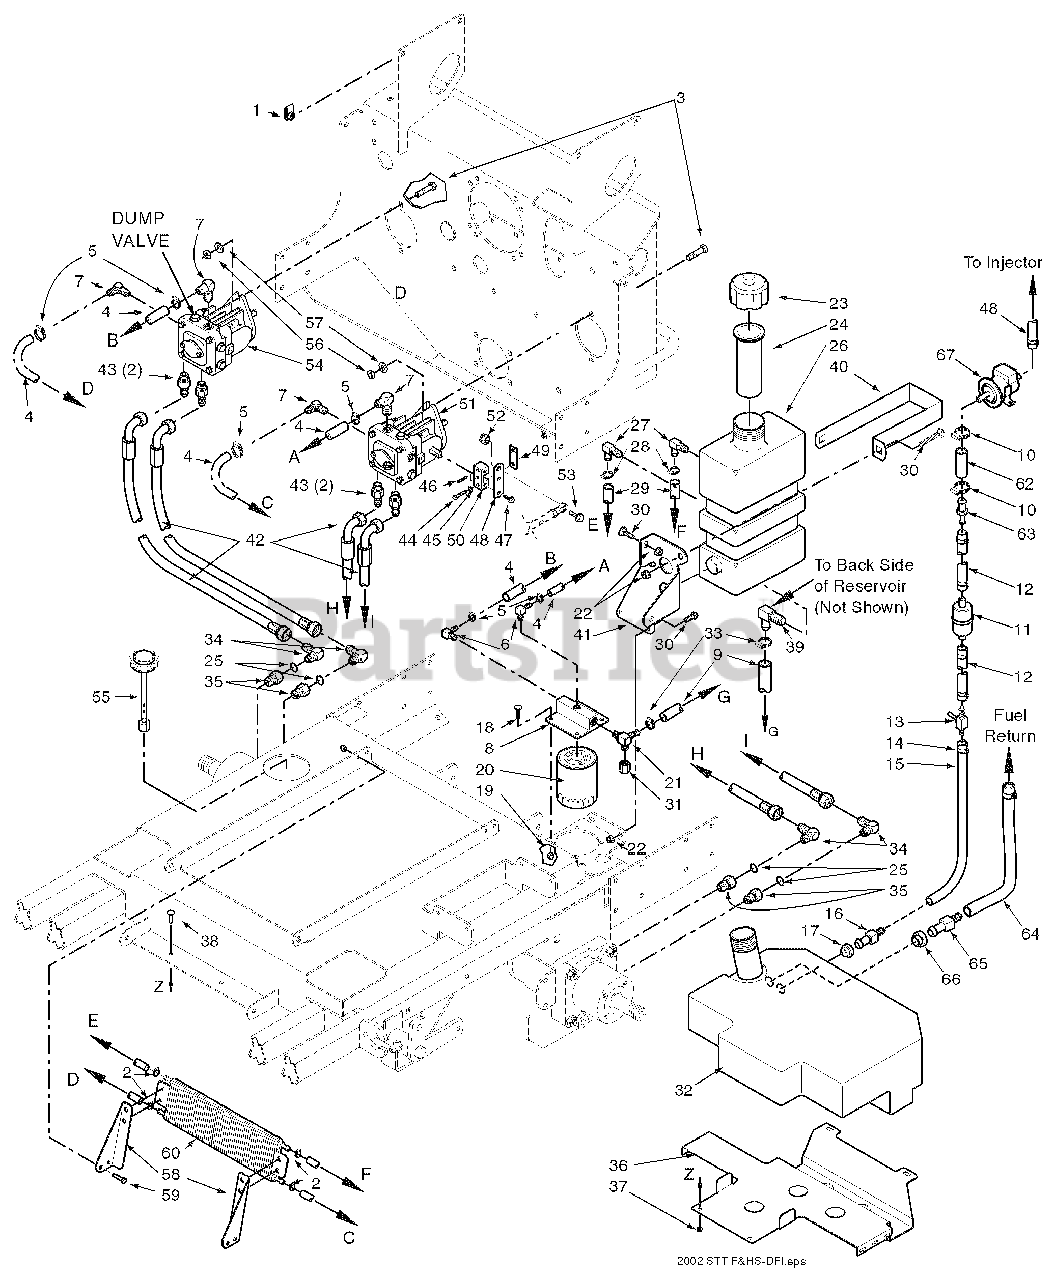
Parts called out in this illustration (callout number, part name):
1	U-Nut 1/4-20
2	Hose Clamp, 0.69 dia.
3	Bolt, Hex Head 1/4-20 x 2.0"
4	Hose, 3/8" ID Pushlock
5	Clamp, Hose 1/2"
6	Elbow, 90 Degree - 1/4 NPT x 3/8" Hose
7	Elbow, 90 Degree - 9/16 O-ring x 3/8" Hose
8	Oil Filter Base
9	Hose Assembly, 1/2" ID
10	Clamp, .87 max Dia.
11	Fuel Filter, Kawasaki
12	Fuel Hose, 5/16" ID. Non-Perm.
13	Valve, Shutoff Kawasaki
14	Clamp, Fuel Hose
15	Fuel Hose, 5/16" ID. Non-Perm.
16	Hose Fitting
17	Bushing
18	Bolt, Hex Head 5/16-18 x1.0" Zinc
19	Nut, Serrated Flange 5/16-18
20	Oil Filter
21	Tee, 3/4 O-ring x JIC x 1/2" Hose
22	Nut, Hex Elastic Stop 1/4-20
23	Cap, Hydraulic Tank
24	Insert, Filler Neck
25	O-Ring
26	Oil Reservoir Assembly
27	Elbow, 90 Degree .38 Hose
28	Hose Clamp, 0.69 dia.
29	Hose, 3/8" ID, Pushlock
30	Screw, Phillips Head, 1/4-20
32	Fuel Tank Assembly
33	Clamp, Hose
34	Elbow, 90 Degree, 7/8-14 THD
35	Bushing, 7/8-14 JIC x 3/4-16 O-Ring
36	Support Bracket, Fuel Tank
37	Nut, 5/16-18 Serrated Flange
38	Bolt, Carraige 1/4-20 x 3/4"
39	Elbow, 90 Degree
40	Strap, Hydraulic Tank
41	Support Bracket, Hydraulic Tank
42	Hose Assembly, Pump
43	Union, 3/4-16 JIC x 3/4-16 O-ring
44	Bolt, Hex Head, 1/4-20 x 1-14"
45	Lockwasher, 1/4" Spring
46	Roll Pin, Spring 3/16 x 3/4"
47	Bolt, Hex Serrated Flange, 1/4-20 x 3/4"
48	Fuel Hose, 5/16" ID.
49	Clamp Plate, Pump Control
50	Block, Pump Control
51	Pump, Left Hand, BDP-16A
52	Nut, Hex, Elastic Stop 3/8-16
53	Bolt, Hex Head, 3/8-16 x 1-1/4
54	Pump, Right Hand, BDP 16A
55	Cap, Fuel Tank W/Gauge
56	Nut, Hex Elastic Stop 3/8-16
57	Flatwasher, 3/8" Grade 8
58	Mounting Bracket - LH, Oil Cooler
59	Bolt, Hex Head 5/16-18 x 3/4"
60	Cooler, Oil
61	Clamp, .69 Dia.
62	Hose, Fuel Line
64	Hose, 1/4" Fuel Line Non-Perm.
65	Fitting, Hose
66	Bushing
68	Fuel Hose, 5/16" ID. Non-Perm.
